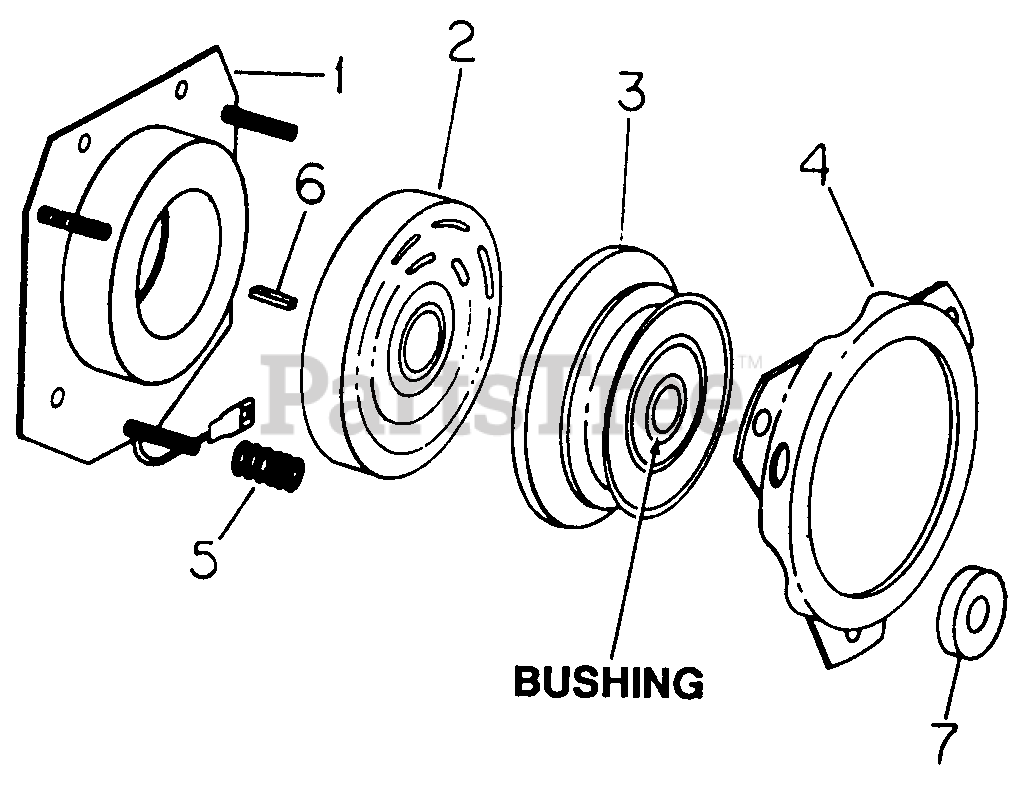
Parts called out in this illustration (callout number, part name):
1	Field Assembly
5	Kit, Spring
6	Key, 1/4 X 5/8 Sq Parallel
